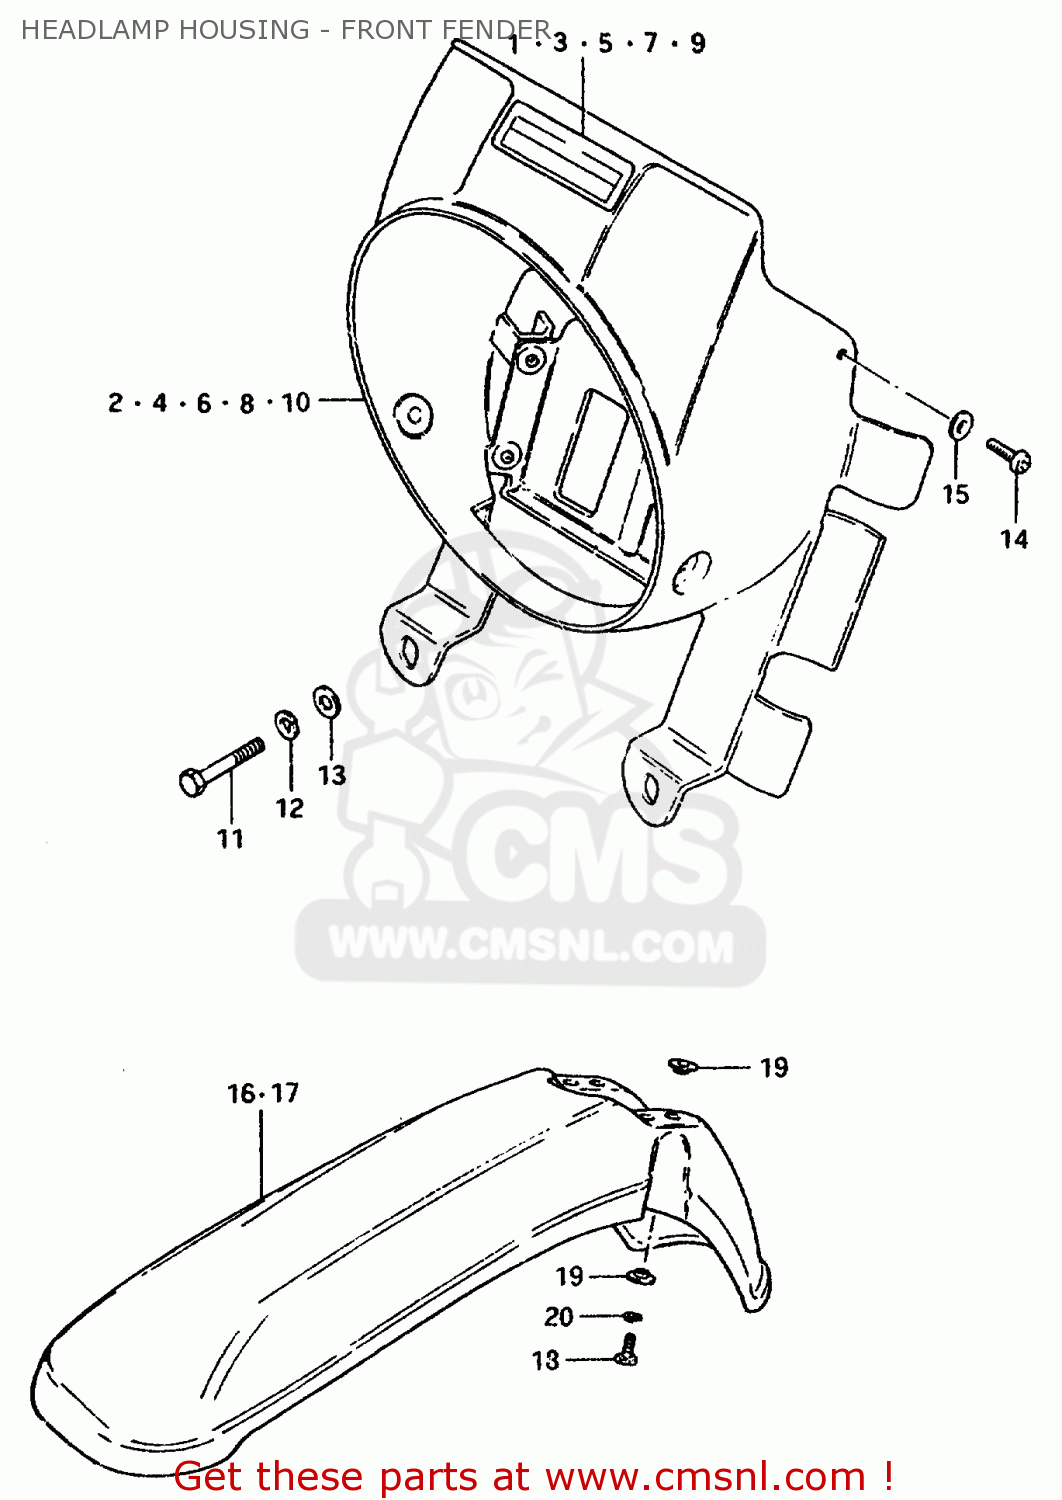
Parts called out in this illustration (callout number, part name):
1	HOUSING, HEADLAMP
2	TAPE, HOUSING
3	HOUSING, HEADLAMP
4	TAPE, HOUSING
5	HOUSING, HEADLAMP
6	TAPE, HOUSING
7	HOUSING, HEADLAMP
8	TAPE, HOUSING
9	HOUSING, HEADLAMP
10	TAPE, HOUSING
11	BOLT
12	LOCK WASHER
13	WASHER
14	SCREW
15	WASHER (5.5X16X1.2)
16	FENDER, FRONT
17	FENDER, FRONT
18	BOLT, UPPER
19	SPACER
20	LOCK WASHER
